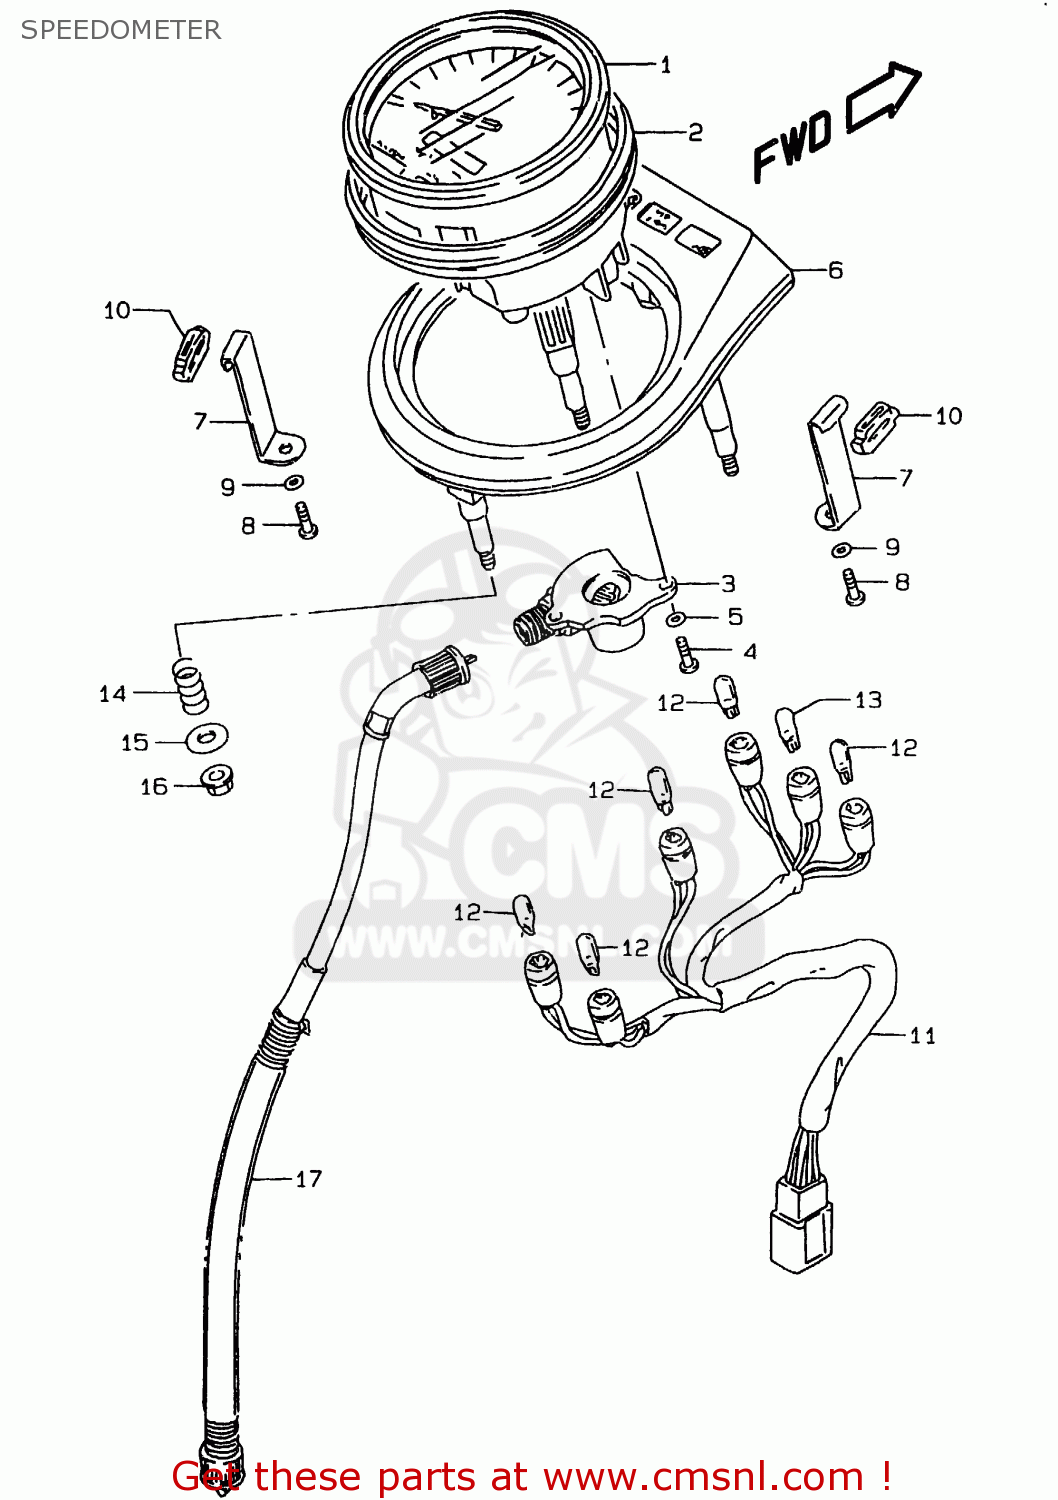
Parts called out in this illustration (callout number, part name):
1	SPEEDOMETER(KILO)
2	CUSHION,METER
3	BOX,GEAR
4	SCREW
5	WASHER,LOCK
6	HOOD,METER
7	BRACKET,METER
8	SCREW
9	WASHER,LOCK
10	CUSHION
11	SOCKET,METER
12	BULB(12V3W,T6.5)
13	BULB(12V1.7W,T6.5)
14	SPRING
15	WASHER(5.5X14X1.2)
16	NUT
17	CABLE ASSY,SPEEDOMETER
